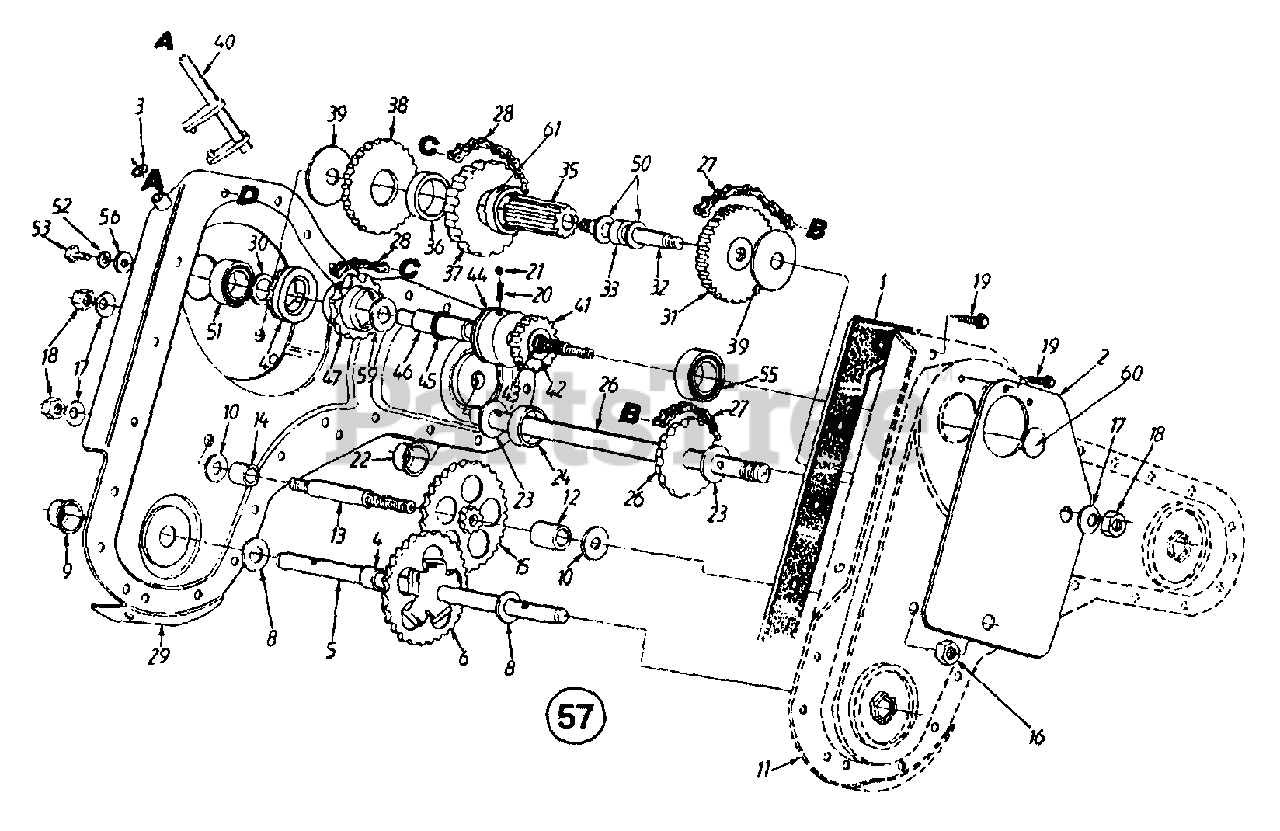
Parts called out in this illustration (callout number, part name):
1	Chain Case Gasket
4	Spacer .735" I.D. x .886" O.D.
5	Wheel Shaft
6	Spur Gear 46T
8	Fl-Wash .76" I.D. x 1.5" O.D.
10	Thr. Wash. .445 I.D. x 1.92 O.D. x
13	Jack Shaft 2.06" Lg.
14	Spacer .635" I.D. x 1" O.D. x .37" Thk.
15	Gear Idler Ass'y.
16	Hex Patch L-Nut 7/16-20 Thd.
17	Bell-Wash. .45" I.D. x 1" O.D.
18	Hex Nut 7/16-20 Thd.
19	Hex Wash. Hd. TT-Tap Scr. 1/4-20 x .5" Lg.
20	Spring Detent
22	Shaft Seal
23	Thrust Wash. 1.03" I.D. x 1.62"
24	Spacer 1" I.D. x 2" O.D. x .5" Thk.
26	Tine Shaft Ass'y.
27	Chain #50 5/8" Pitch x 52 Links - Endless
28	Chain - #41 1/2" Pitch x 30 Links - Endless
30	Fl-Wash. 7/16" I.D. x 1-3/8" O.D.
31	Gear and Sprocket Ass'y.
32	Jack Shaft 5" Lg.
33	Spacer .636" I.D. x .86" O.D.
35	Spur Gear 10T
36	Spacer 1.5" I.D. x 1.76" O.D.
37	Sprocket - #41 Chain
38	Reverse Gear 46T
39	Thrust Wash. .445" I.D. x 1.92"
40	Shifter Ass'y.
41	Spur Gear 17T
42	Fl-Wash. .69" I.D. x 1.06" O.D.
44	Clutch Collar
45	Retaining Ring .875" Shaft
47	Sprocket 11T
49	Spur Gear 16T
50	Fl-Wash. 5/8" I.D. x 1" O.D.
51	Ball Bearing .669" I.D.
52	L-Wash. 3/4" I.D.
53	Hex Bolt 1/4-20 x .62" Lg.
55	Ball Bearing
56	Fl-Wash. .281" I.D. x .875" O.D.
57	Gear Case Ass'y. Comp.
59	Fl-Wash. 88" I.D. x 1.5" O.D.
61	Spacer 1.52" I.D.
